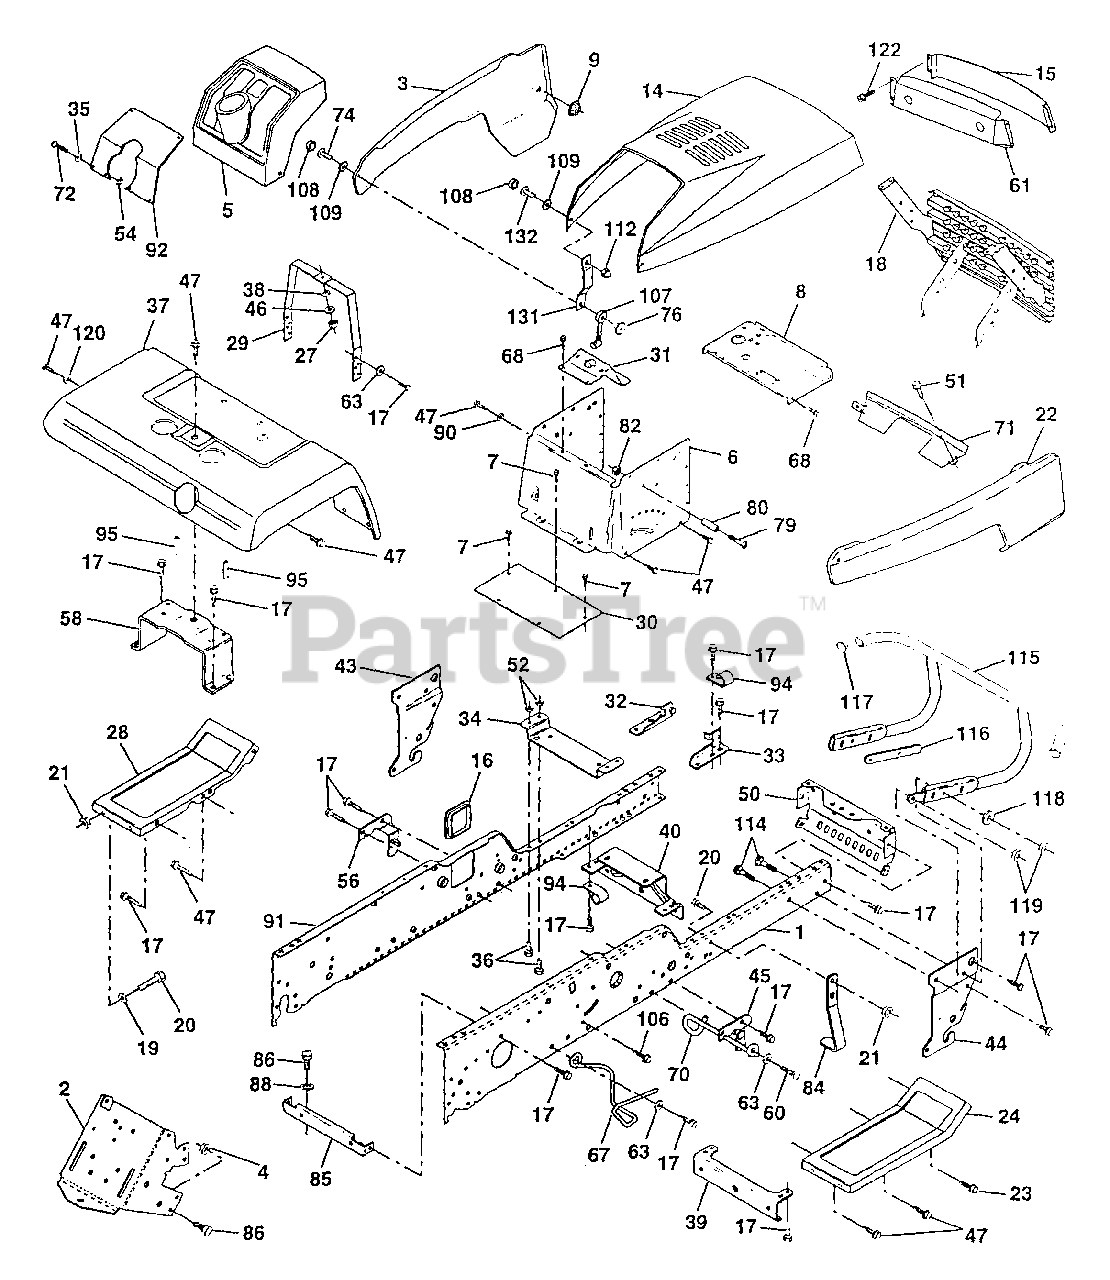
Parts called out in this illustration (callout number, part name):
1	Rail, Frame RH (AYP part number)
2	Drawbar, Gt (AYP part number)
3	Panel Asm., Side LH
4	Nut, Lock Hex 7/16 Unc
5	Dash, Plastic Black
6	Dash Asm., Lower
7	Screw, Thd Cut 1/4-20 x 1/2
8	Support, Battery (AYP part number)
9	Nut Pal
14	Hood Asm., Pnt
15	Lens/Clip Asm. Bar Clear
16	Cover, Access
17	Screw, Thdrol 3/8-16 x 3/4
18	Grille
19	Washer 13/32 x 13/36 x 12 Ga.
20	Bolt, Fin Hex 3/8-16 x 1
21	Nut, Crownlock 3/8-16
22	Panel Asm., Side RH (AYP part number)
23	Screw Thdrol 3/8-16 x 1
24	Footrest, RH (AYP part number)
27	Nut, Fin Hex 1/4-20
28	Footrest, LH
29	Bracket, Support Dash
30	Saddle
31	Brace, Support Steering
32	Bracket Asm., Frame Pivot Lh
33	Bracket Asm., Frame Pivot Rh
34	Bracket, Engine Support Rear
35	Washer 11/32 x 11/16 x 16 Ga.
36	Bolt, Fin Hex 5/16-18 x 3/4
37	Fender, Pnt.
38	Washer, Lock 1/4
39	Bracket, Axle Front (AYP part number)
40	Bracket, Support Axle/Engine
43	Bracket, Spnsn Front Lh
44	Bracket, Spnsn Front Rh
45	Bracket Asm., Susp Chassis Rh
46	Washer 9/32 x 3/4 x 16 Ga.
47	Screw Thdrol 3/8-16 x 1/2
50	Bracket, Chassis Front
51	Screw Tap Tight 1/4-20 x 1/2
52	Nut, Crownlock 5/16-18
54	Nut 5/16-18
56	Bracket Asm., Susp Chassis Lh
58	Bracket Asm., Fender
60	Screw Thdrol 3/8-16 x 1-1/4
61	Bezel Asm. Pnt. (AYP part number)
63	Washer 13/32 x 3/4 x 14 Ga. (AYP part number)
67	Guide, Belt Gear Dr 97
68	Screw, Thdrol 5/16-18 x 1/2
70	Guide, Belt Mid Span (AYP part number)
71	Strap Grille (AYP part number)
72	Screw, Mach Trhd 5/16-18 x 3/4
74	Screw, Machine #10-24
76	Nut, Weld #10-24
79	Screw, Machine #10-24 x 1/4
80	Spacer, Split
82	Nut #10-24
84	Stop, Over Center Mower
85	Bracket, Support
86	Bolt, Fin Hex 7/16-14 Unc x 1 (AYP part number)
88	Washer, Lock Hvy Hld Sp 7/16
90	Washer, Lock External Tooth 3/8
91	Rail, Frame Lh (AYP part number)
92	Plate, Silkscreen Dash (AYP part number)
94	Clip, Fuel Line
95	Push Nut, Nylon
106	Screw Thdrol Hex Head Zinc Mwr (AYP part number)
107	Latch, Chute Blk
108	Cap, Snap, Black
109	Cap, Waher, Snap
112	Nut, Acorn Hex #10-24
114	Bolt, Carriage 3/8-16 x 1-1/4
115	Bumper Asy
116	Bracket Extension Bumper (AYP part number)
117	Plug Plastic
118	Washer 13/32 x 13/16 x 16 Ga.
119	Nut, Crownlock 3/8-16 UNC
120	Washer 13/32 x 1 x 16 Ga.
122	Screw Lock Spider #8 x 7/8
131	Bracket Support Hood / Panel YP
132	Screw Truss Hd #10-24 x 3/8
